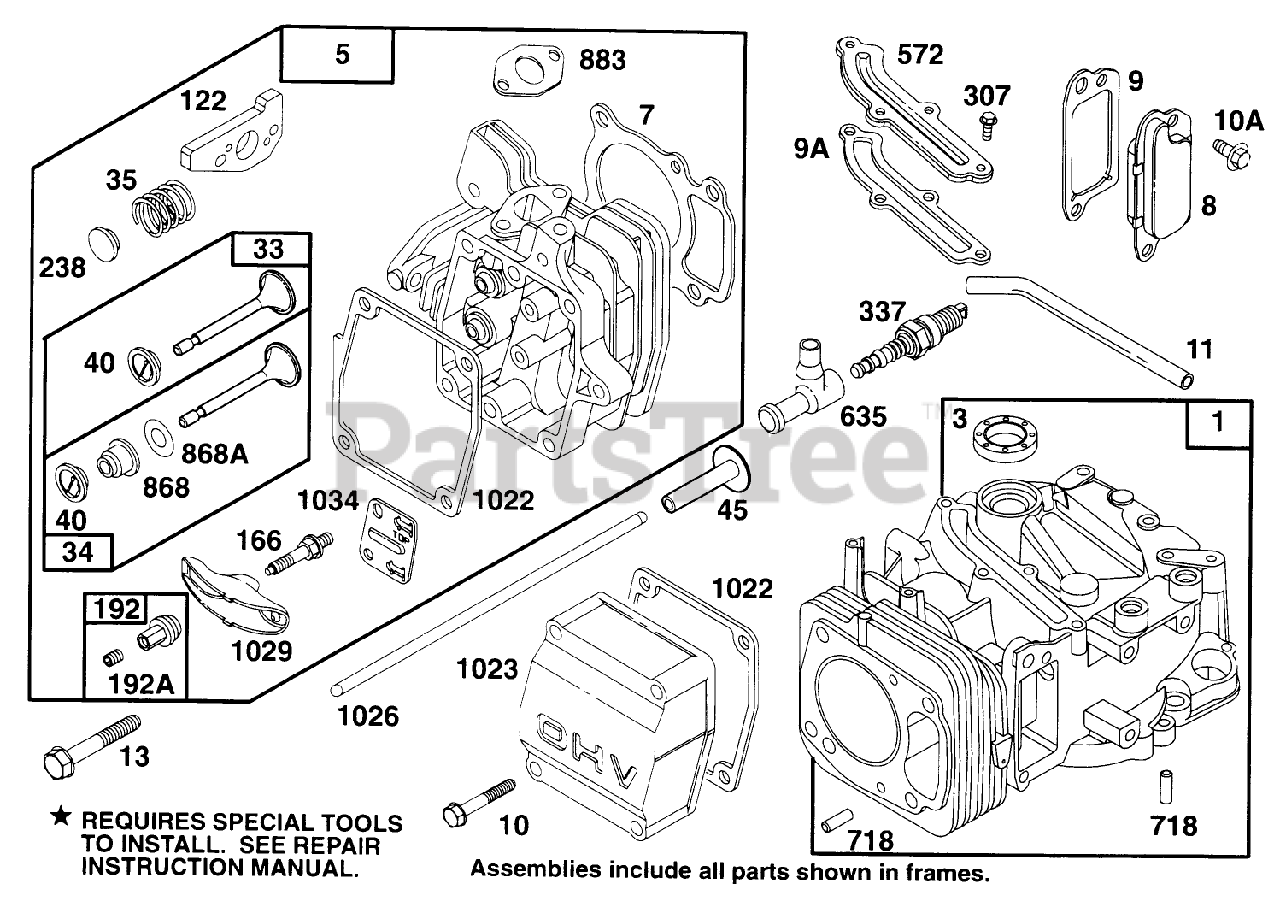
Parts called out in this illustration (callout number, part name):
188	SCREW - HEX HEAD
188A	SCREW - SEM
300	MUFFLER - EXHAUST
346	SCREW - SELF-TAPPING
832	Guard-Muffler
883	EXHAUST GASKET
